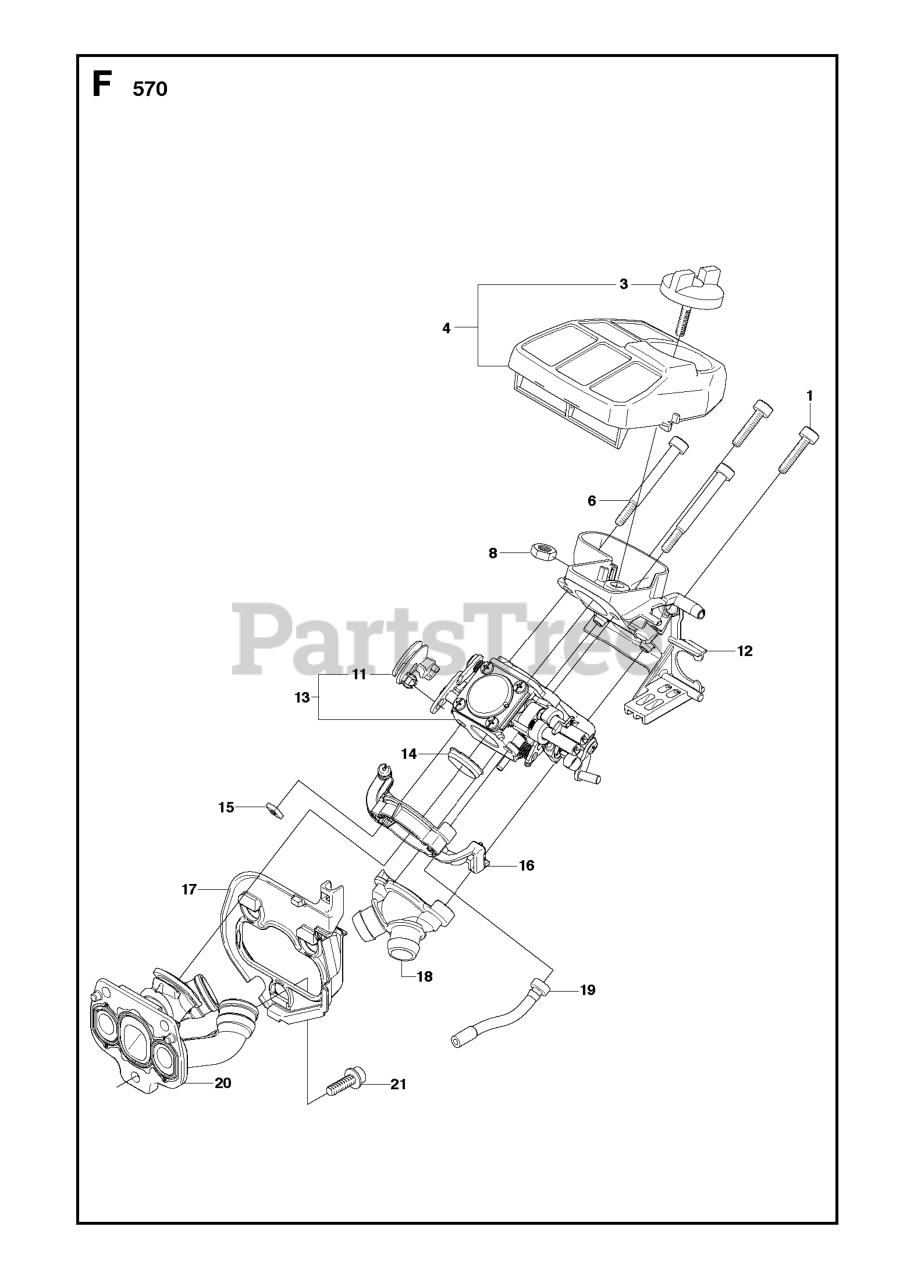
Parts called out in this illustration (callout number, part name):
4	AIR FILTER
6	SCREW 4X46
12	FILTER HOLDER
13	CARBURETTOR
20	PIPE
